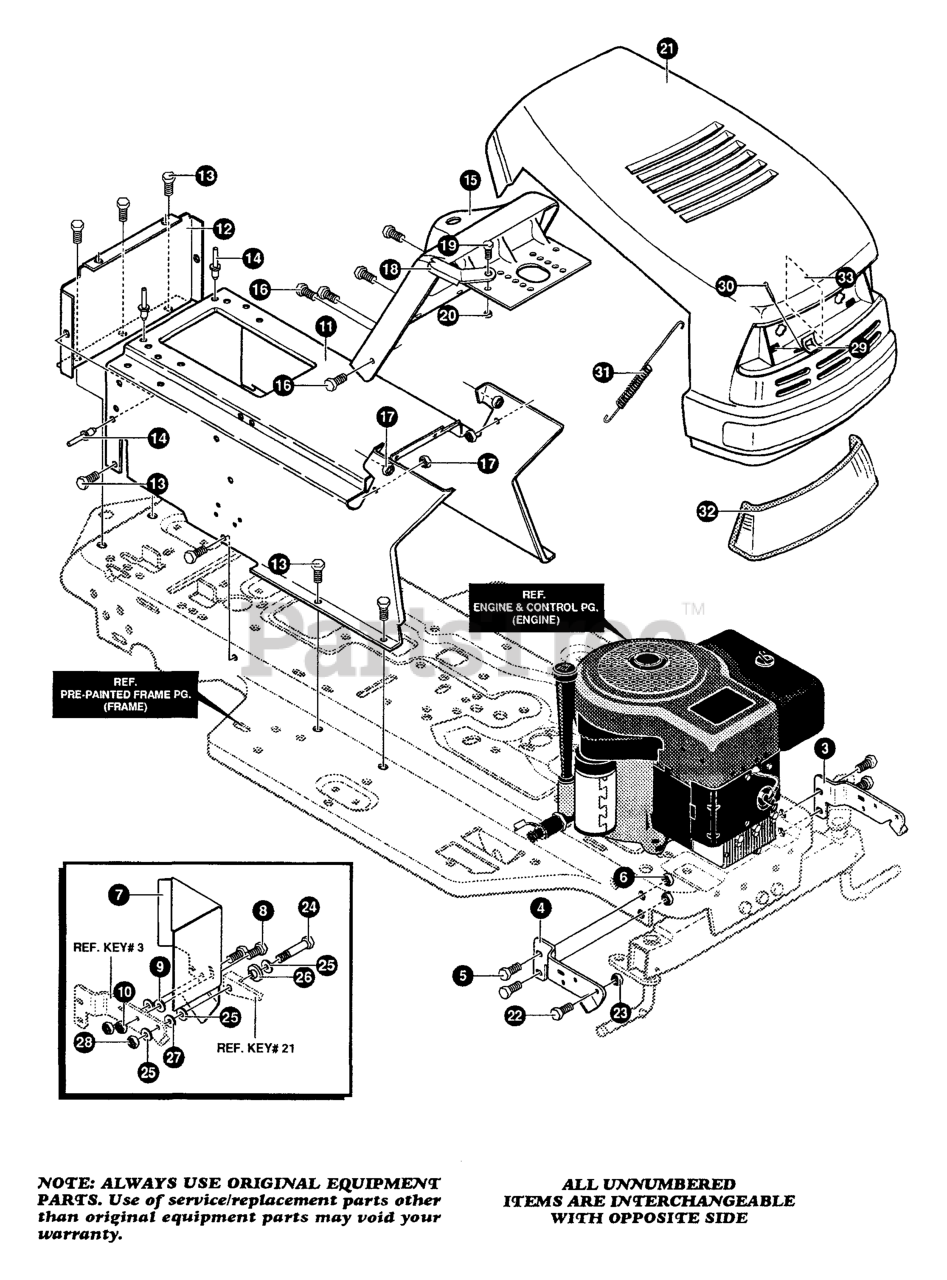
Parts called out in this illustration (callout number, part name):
3	BRACKET, GRILLE SUPPORT, LH
4	BRACKET, GRILLE, RH
5	SCREW, 5/16-18 x 1.00
6	NUT, 5/16-18
7	SHIELD, HEAT
8	SCREW, 1/4-20 X .75
9	WASHER, FLAT .250 X .75 x INSULATE
10	NUT, 1/4-20
12	CONSOLE, REAR COVER
13	SCREW, 1/4-20 X .50
14	RIVET, POP
16	SCREW, 1/4-20 X .75
17	NUT, 1/4-20
18	GUIDE, HOOD
19	SCREW, 1/4-20 x .75
20	NUT, 1/4-20
22	BOLT, .375 X 580
23	NUT, 5/16-18
24	SCREW, 1/4-20 x 1.75
25	WASHER, FLAT .281 X .63 X .065
26	BEARING FLANGED
27	WASHER, FLAT .250 X .75 x INSULATE
28	NUT, 1/4-20
29	ANCHOR, HOOD LANYARD
30	PIN, COTTER
31	SPRING, HOOD LATCH
32	LENS, HEADLAMP
33	FOIL, HEAT REFLECTOR
